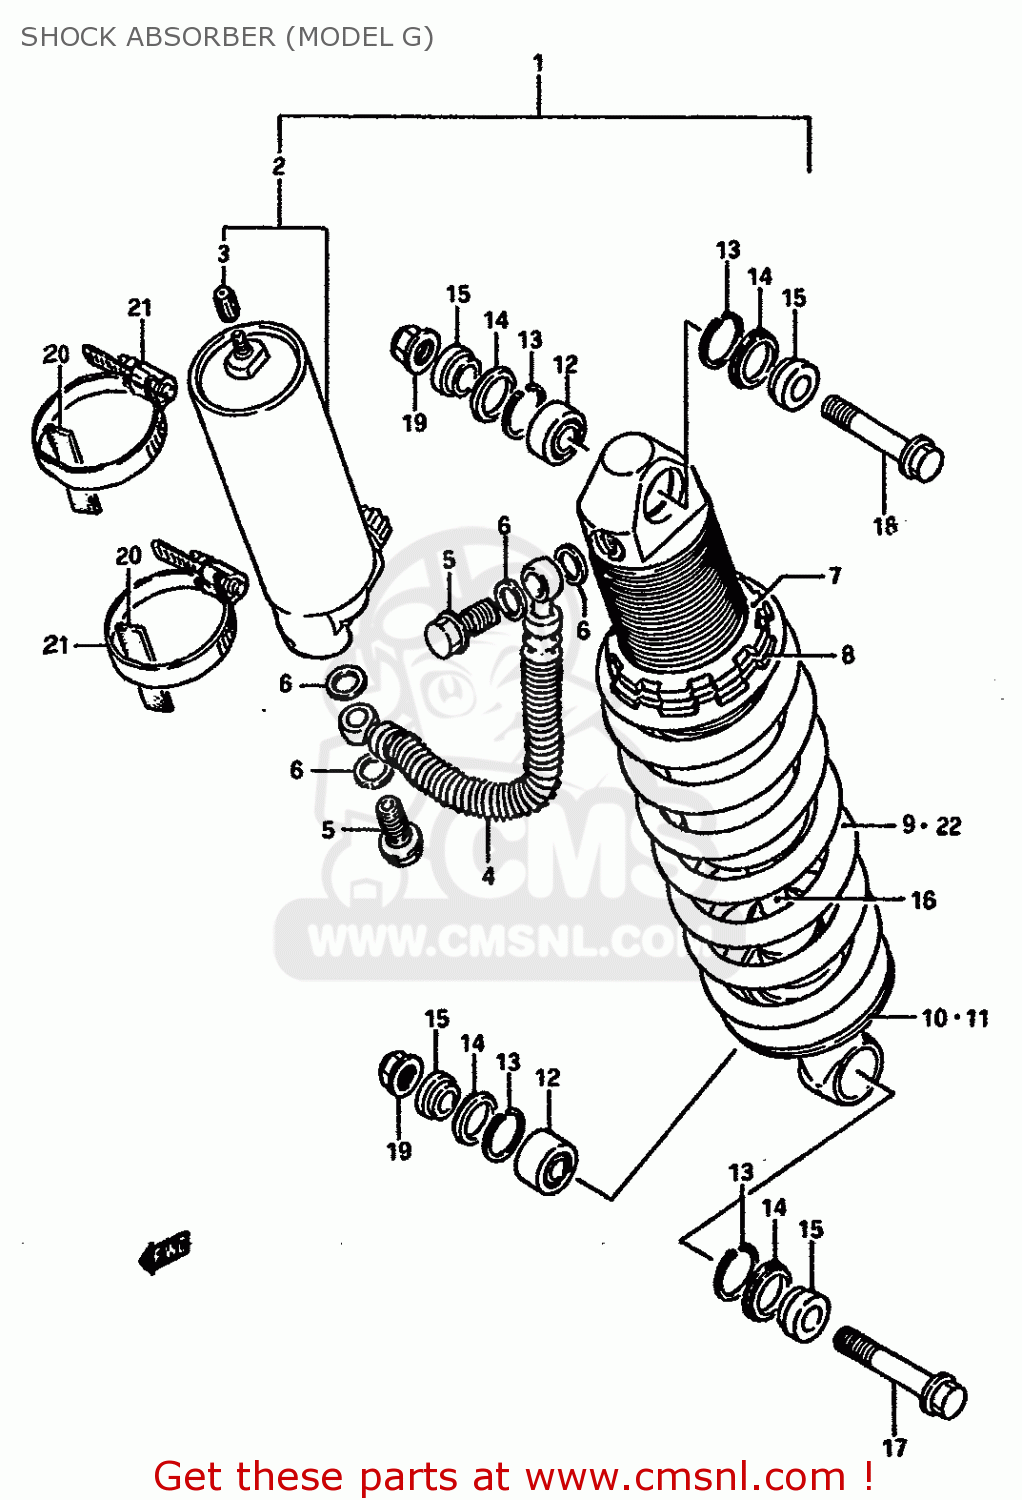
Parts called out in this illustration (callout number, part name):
1	ABSORBER ASSEMBLY,REAR SHOCK
2	TANK
3	CAP
4	HOSE
5	BOLT,REAR SHOCK ABSORBER
6	GASKET (NAS)
7	NUT
8	GUIDE,SPRING
9	SPRING
10	WASHER
11	GUIDE,SPRING
12	BEARING,REAR SHOCK ABSORBER
13	RING
14	SEAL,DUST RR SHOCK ABSORBER
15	COLLAR
16	ROD,PISTON
17	BOLT,REAR SHOCK ABSORBER
18	BOLT,UPPER
19	NUT
20	CUSHION,REAR SHOCK ABSORBER
21	CLAMP
22	SPRING
